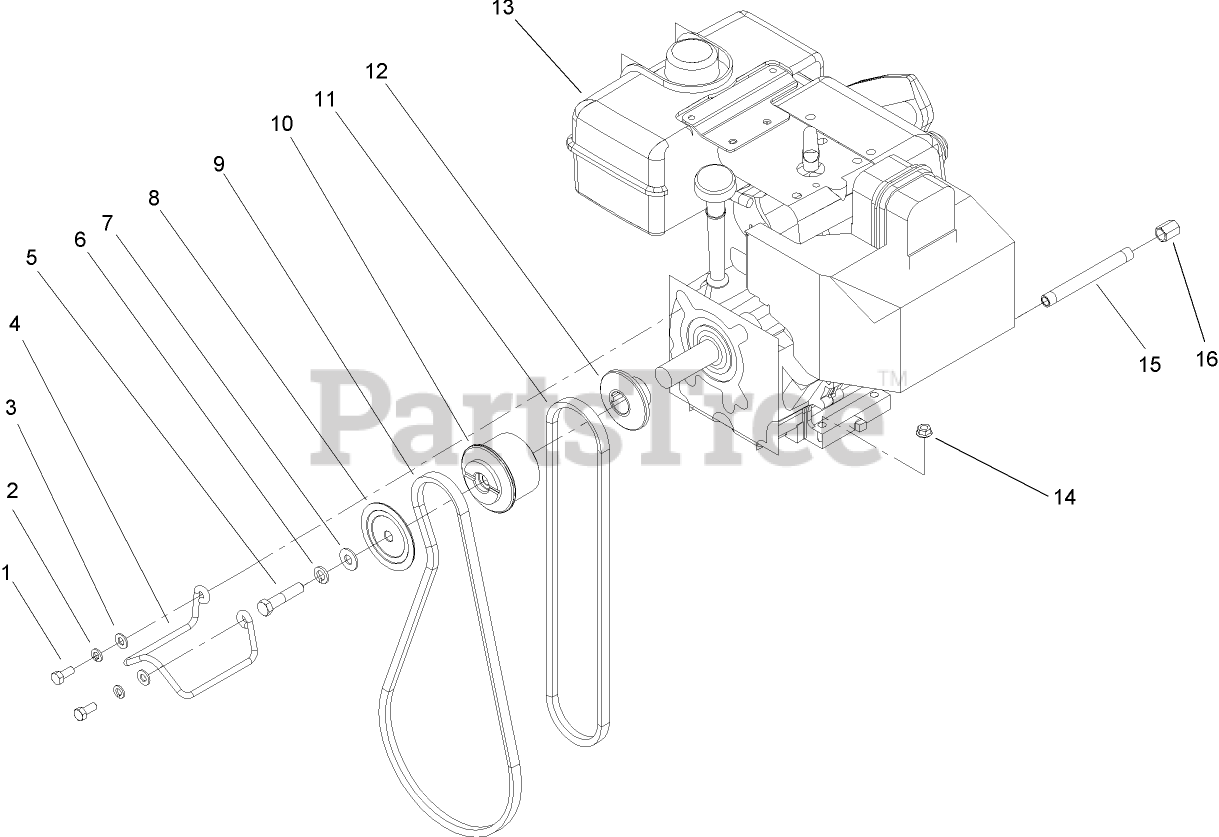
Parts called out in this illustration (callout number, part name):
1	SCREW-HH
2	WASHER-LOCK
3	WASHER-PLAIN
5	SCREW-HH
6	WASHER-LOCK
7	WASHER-FLAT
8	SHEAVE-HALF, IMPELLER
9	BELT-V
10	PULLEY-ENGINE, CENTER
11	V BELT-TRACTION
12	SHEAVE-HALF, TRACTION
13	Loose Parts Package
14	NUT-HF
15	NIPPLE-PIPE
16	CAP-PIPE
